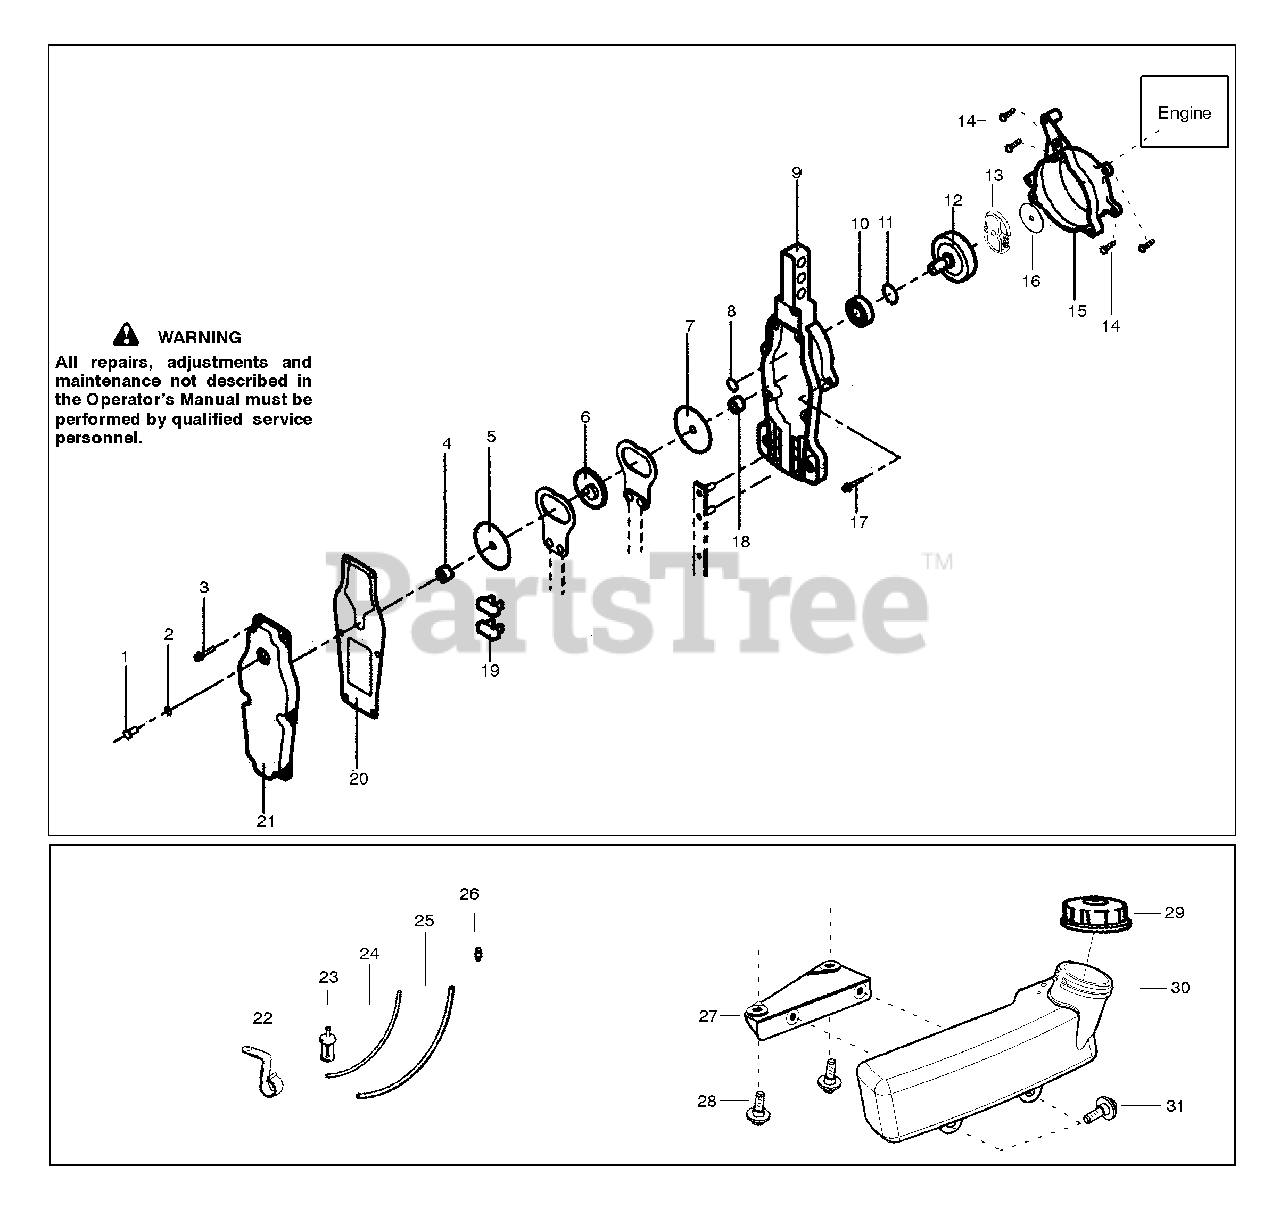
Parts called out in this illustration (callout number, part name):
1	Plug-Grease
2	O-ring
3	Socket Screw Flange
5	Fixing Plate
7	Fixing Plate
8	C-Snapring for Shaft
9	Cam Case
11	C-Snapring for Hole
12	Clutch Drum C.P
13	Kit-Clutch Assy.
15	Engine Base
16	Washer-Clutch
17	Socket Screw Flange
19	Felt Packing
21	Cam Case Cover
22	Clip-Wire
23	Assy-Fuel Pickup
24	Kit-Fuel Line
25	Kit-Fuel Line
26	Fitting-Fuel Line
27	Bracket-Tank
28	Screw-Retainer
29	Assy-Fuel Cap
30	Assy-Fuel Tank
31	Screw-Retainer
